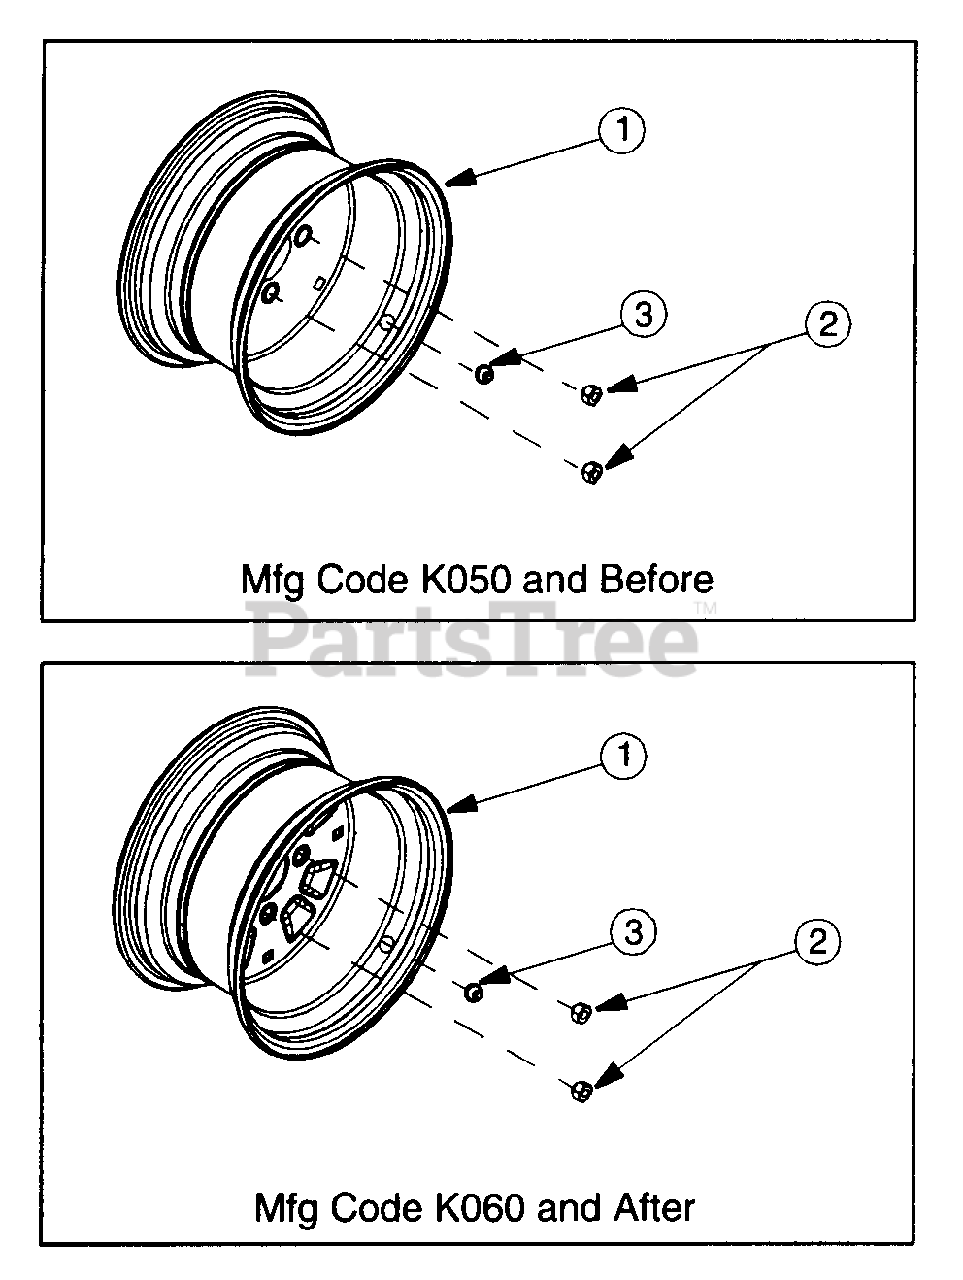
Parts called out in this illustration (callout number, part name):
1	Rim Assy, Rear
2	Nut, Lug, 7/16-14
3	Valve, Tubeless Air
